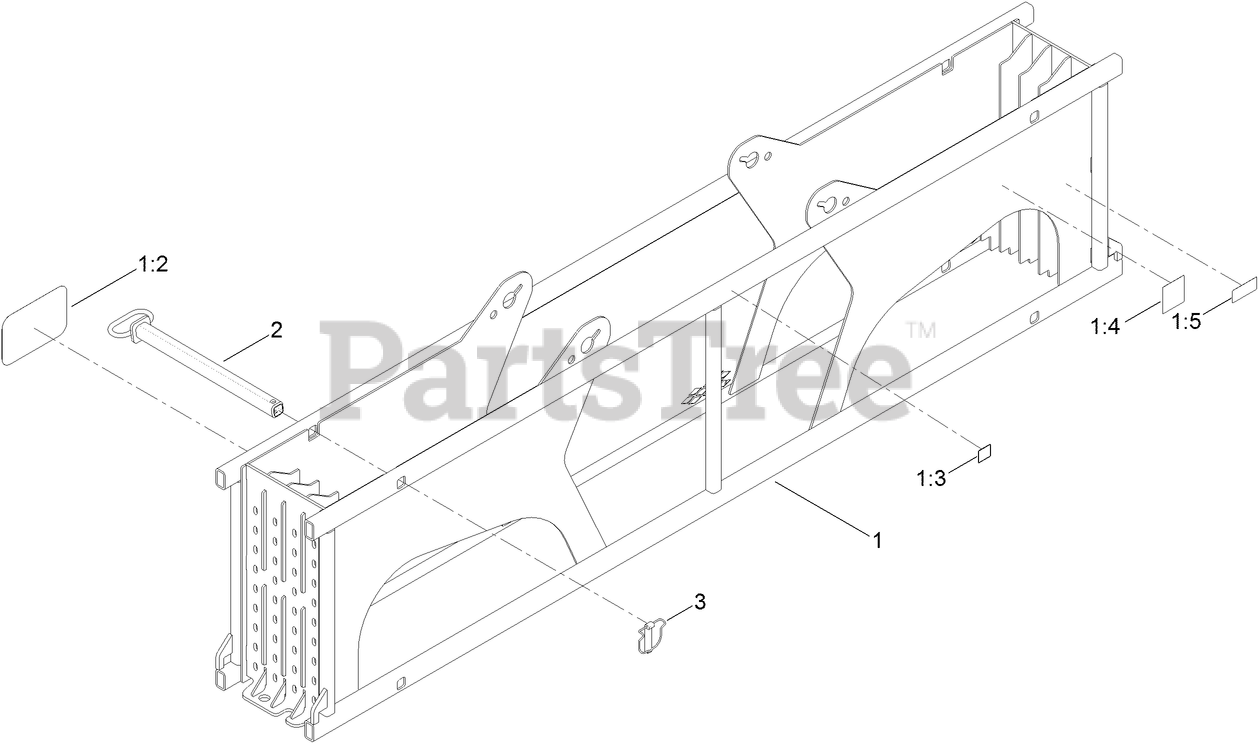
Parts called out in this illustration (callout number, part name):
1	ROD BOX ASM
1:3	DECAL-WEIGHT, ROD BASKET
1:4	DECAL-WARNING, CRUSHING
1:5	DECAL-DANGER, ENTANGLEMENT
2	PIN-ROD BOX
3	PIN-KLIK
